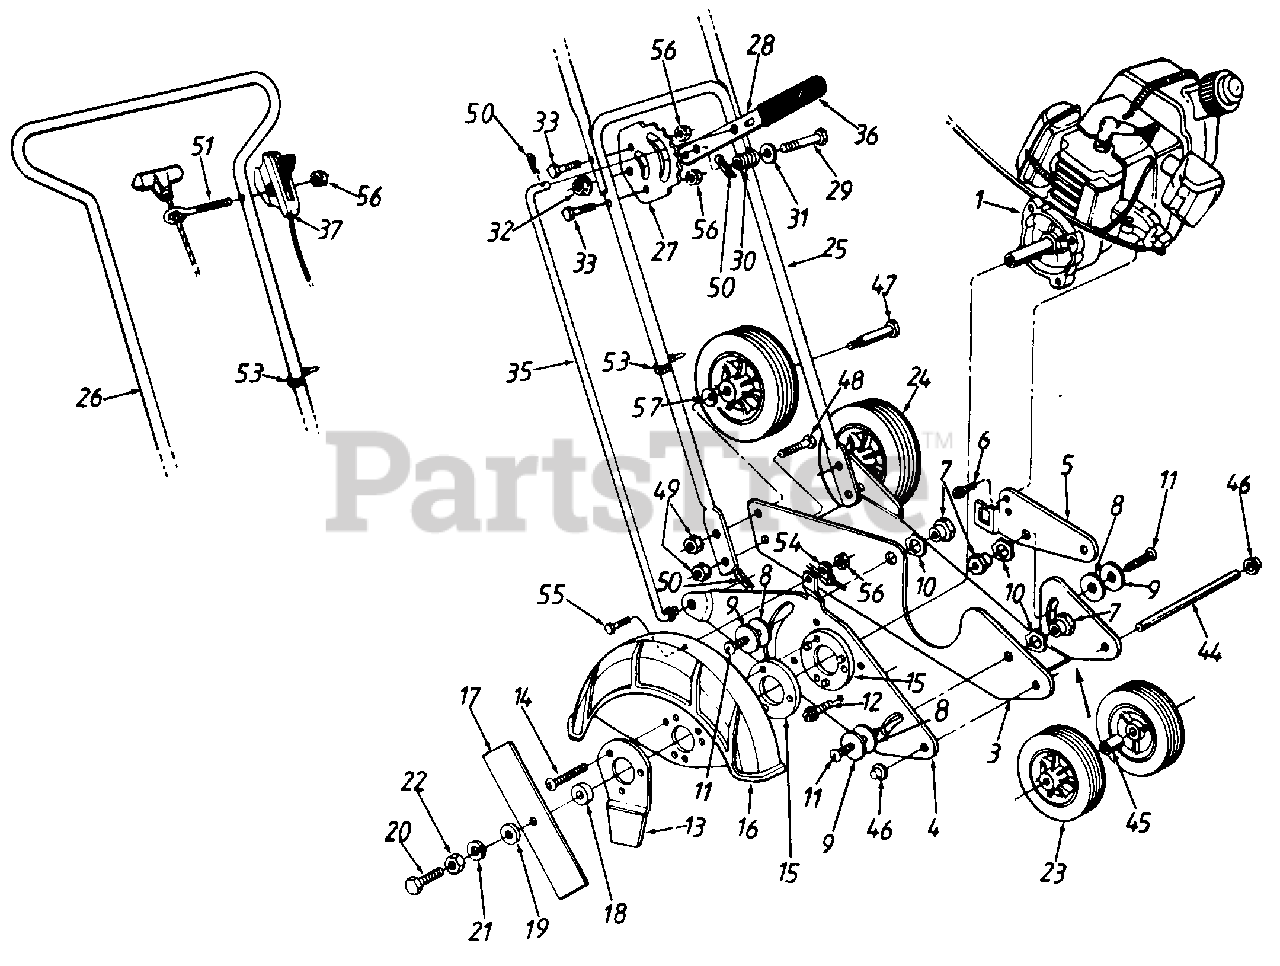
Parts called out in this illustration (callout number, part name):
1	ENGINE
3	EDGER BASE
4	SIDEPLATE
5	ENGIN'E SUPPORT BRKT.
6	HEX WASH. HD. SCR. #8-32 x .625"
7	SHLD. NUT 5/16-18 THD.
8	THRUSH WASH. .819n I.D. x 1.25 O.D. x .05
9	FL-WASH. .319 I.D. x 1.25" O.D. x .048"
10	WAVE-WASH. .53" x.78" x .013"
11	TRUSS MACH. SCR. 5/16-18 x .75" LG.
12	HEX WASH. HD. SCR. 1/4-20 x .50" LG.
13	EDGE GUIDE
14	TRUSS MACH. SCR. #10-32 x 1.0" LG.
15	SPACER - BLADE GUARD
16	BLADE GUARD
17	BLADE
18	SPACER .39" I.D. x l" O.D. x .375"
19	WASHER .406" I.D. x .812" O.D. x .125"
20	HEX BOLT 3/8-24 x 1.5 LG.-GR. 5
21	L-WASH. 3/8" I.D. (H.D.)
22	HEX NUT 3/8-24 THD.
23	5" WHEEL
24	6" WHEEL
25	LOWER HANDLE
26	UPPER HANDLE
27	RATCHET PLATE
28	RATCHET PLATE HANDLE
29	HEX BOLT 5/16-18 x 1.5" LG.
30	SPRING .5" I.D. x .75n O.D. x 1" LG.
31	FL-WASH. .349" I.D. x .879 O.D. x .063
32	FLANGE TOP L-NUT 5/16-18 THD.
33	HEX BOLT 1/4-20 x 1.375 LG.
35	DEPTH CONTROL ROD
36	VINYL GRIP
37	CONTROL CHOKE ASS'Y.
44	AxLE TUBE
45	SPACER
46	PUSHNUT RETAINER
47	SHLG. BOLT .50 DIA. x l.7n
48	HEX BOLT 3/8-16 x .75 LG.
49	FLANGE L-NUT 3/8-16 THD.
50	COTTER PI
51	ROPE GUIDE EYEBOLT
53	CABLE TIE
54	CLAMP
55	HEX BOLT 1/4-20 x .8" LG.
56	HEX INS. L-NUT 1/4-20 THD.
57	BELL-WASH. .38 I.D. x . 88 O.D.
